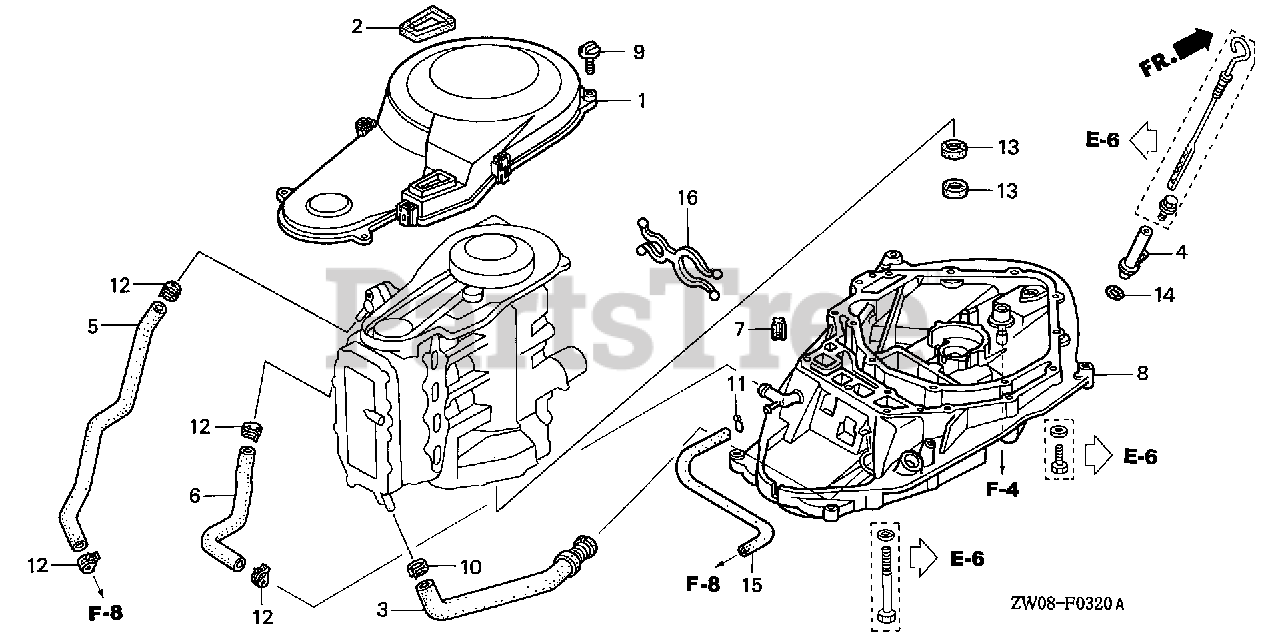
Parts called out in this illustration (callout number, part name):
1	COVER, TIMING BELT (UPPER)
2	RUBBER, SEAL
4	PIPE, OIL LEVEL
5	HOSE, FLUSHING WATER
6	HOSE, WATER BYPASS
7	RUBBER, SEAL
8	CASE, MOUNT *NH8* (DARK GRAY)
9	BOLT, TIMING BELT COVER
10	CLAMP, TUBE (D22)
11	CLIP, TUBE (B8)
12	CLAMP, TUBE (D18.8)
13	SEAL, WATER (22X35X7)
14	O-RING (11.5X3.5)
15	BULK HOSE, VACUUM (4.5X1000) (4.5X290)
16	CLIP, PURSE LOCK
